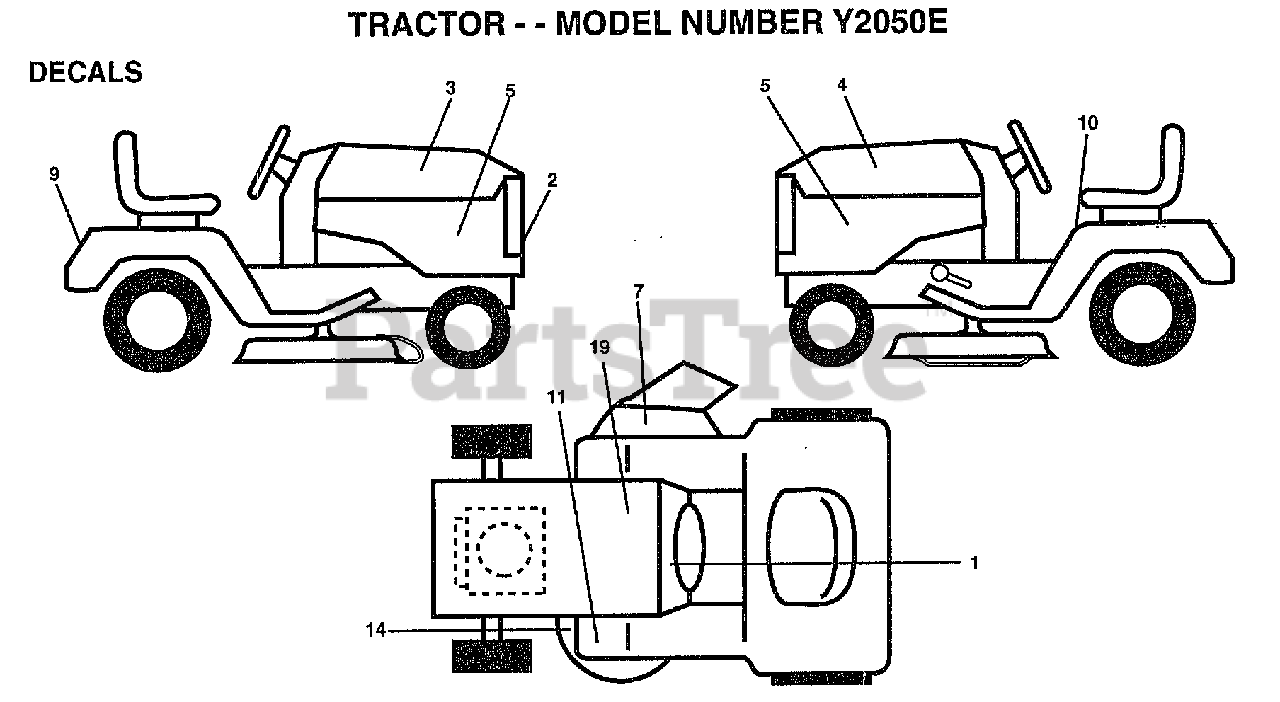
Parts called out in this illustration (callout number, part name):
1	DECAL.DASH.INSTR.
2	DECAL.GRILL.YARDP
4	DECAL HOOD LH
5	DECAL.PANEL.SIDE
7	"DECAL, WARNING"
10	DECAL CAUTION
11	DECAL T
14	"DECAL.V.BELT.44"""
19	DECAL
